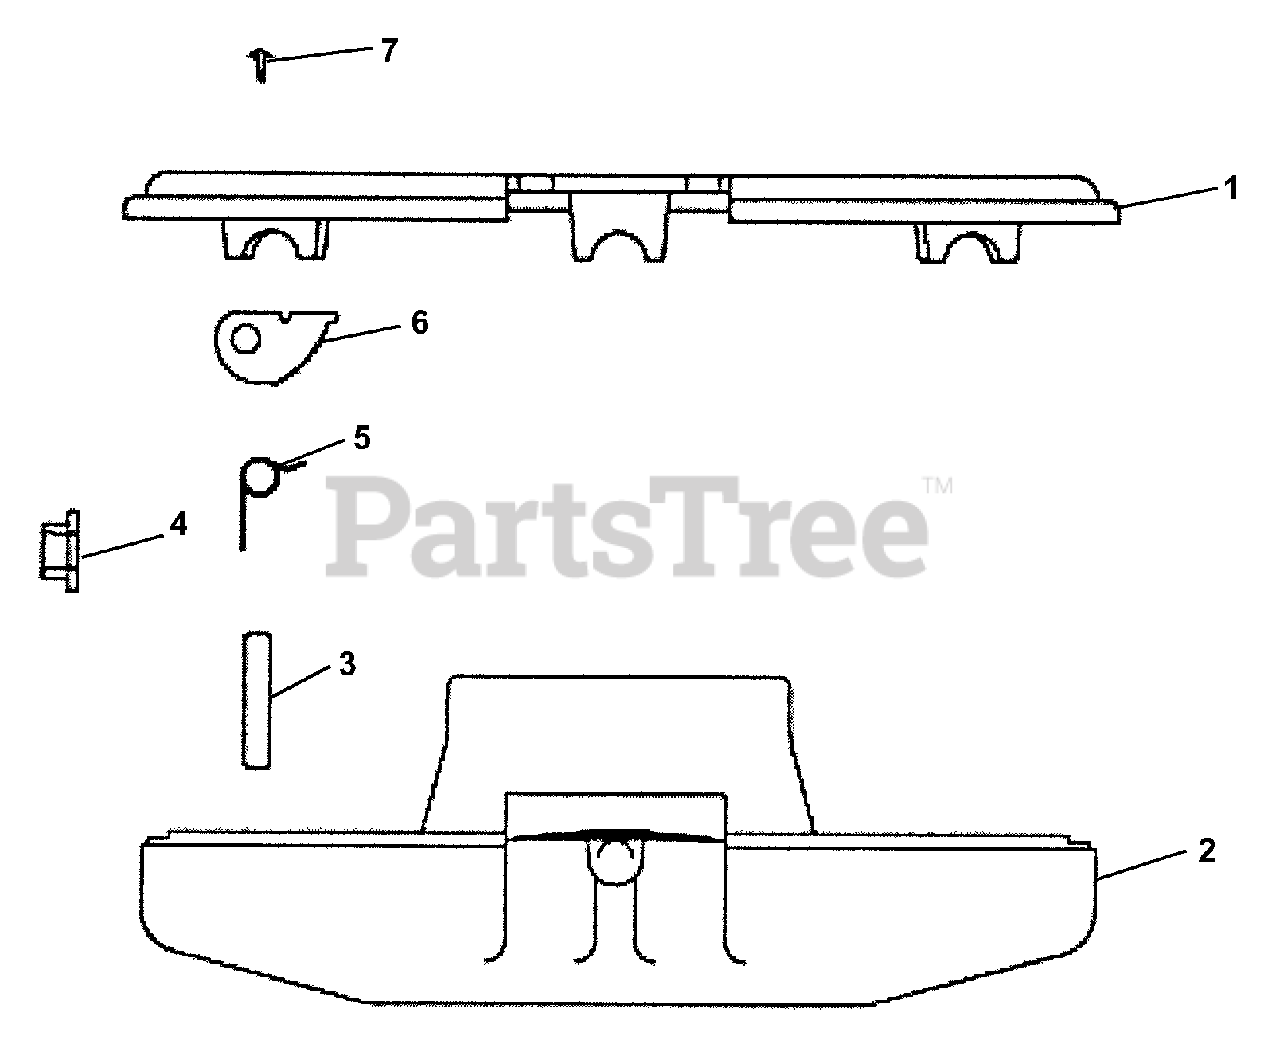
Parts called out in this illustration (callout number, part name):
1	COVER - TOP
2	COVER - BOTTOM
3	SHAFT
5	SPRING
6	CAM
7	SCREW
